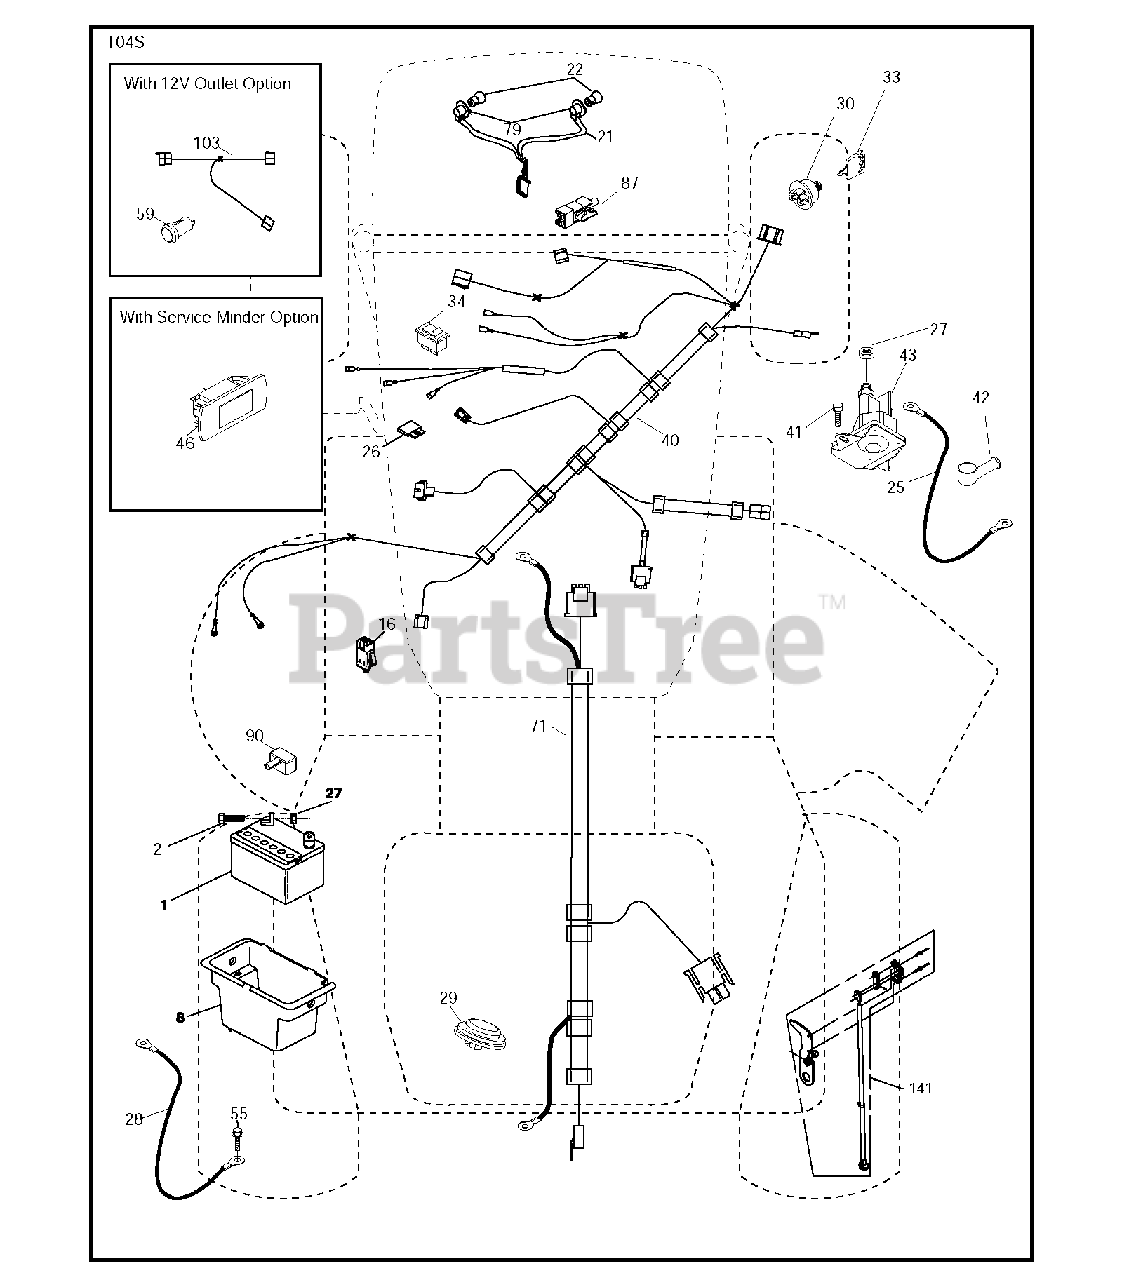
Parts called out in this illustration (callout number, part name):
8	BOX.BATTERY.MNT.REAR.L
16	SWITCH INTERLOOK PUSH-IN
21	HARNESS.LIGHT W/4152J BULBS
22	LIGHTBULB
25	CABLE.STARTER.6GA.BL/RED.14.
26	FUSE 20AMP
27	NUT
28	CABLE.BLACK.18"REAR.BA
29	SWITCH.SEAT.DELTA.OPC.
30	SWITCH.IGN.DELTA.W.LGH.ROS
33	KEY.CHAIN.BLISTER.PACK.GEN.INT
34	SWITCH LT
40	HARNESS IGN. DASH
41	SCREW
42	TERMINAL COVER
43	SOLENOID.W/BRASS.PLUNG
55	SCREW 5/16"
71	HARNESS.IGN.CHASS.TEX.REAR.BAT
79	BULB HOLDER ASM.
87	SWITCH.INTRLCK.CLUTCH.
90	COVER, TERMINAL BATTERY
141	KIT T2.ROS
